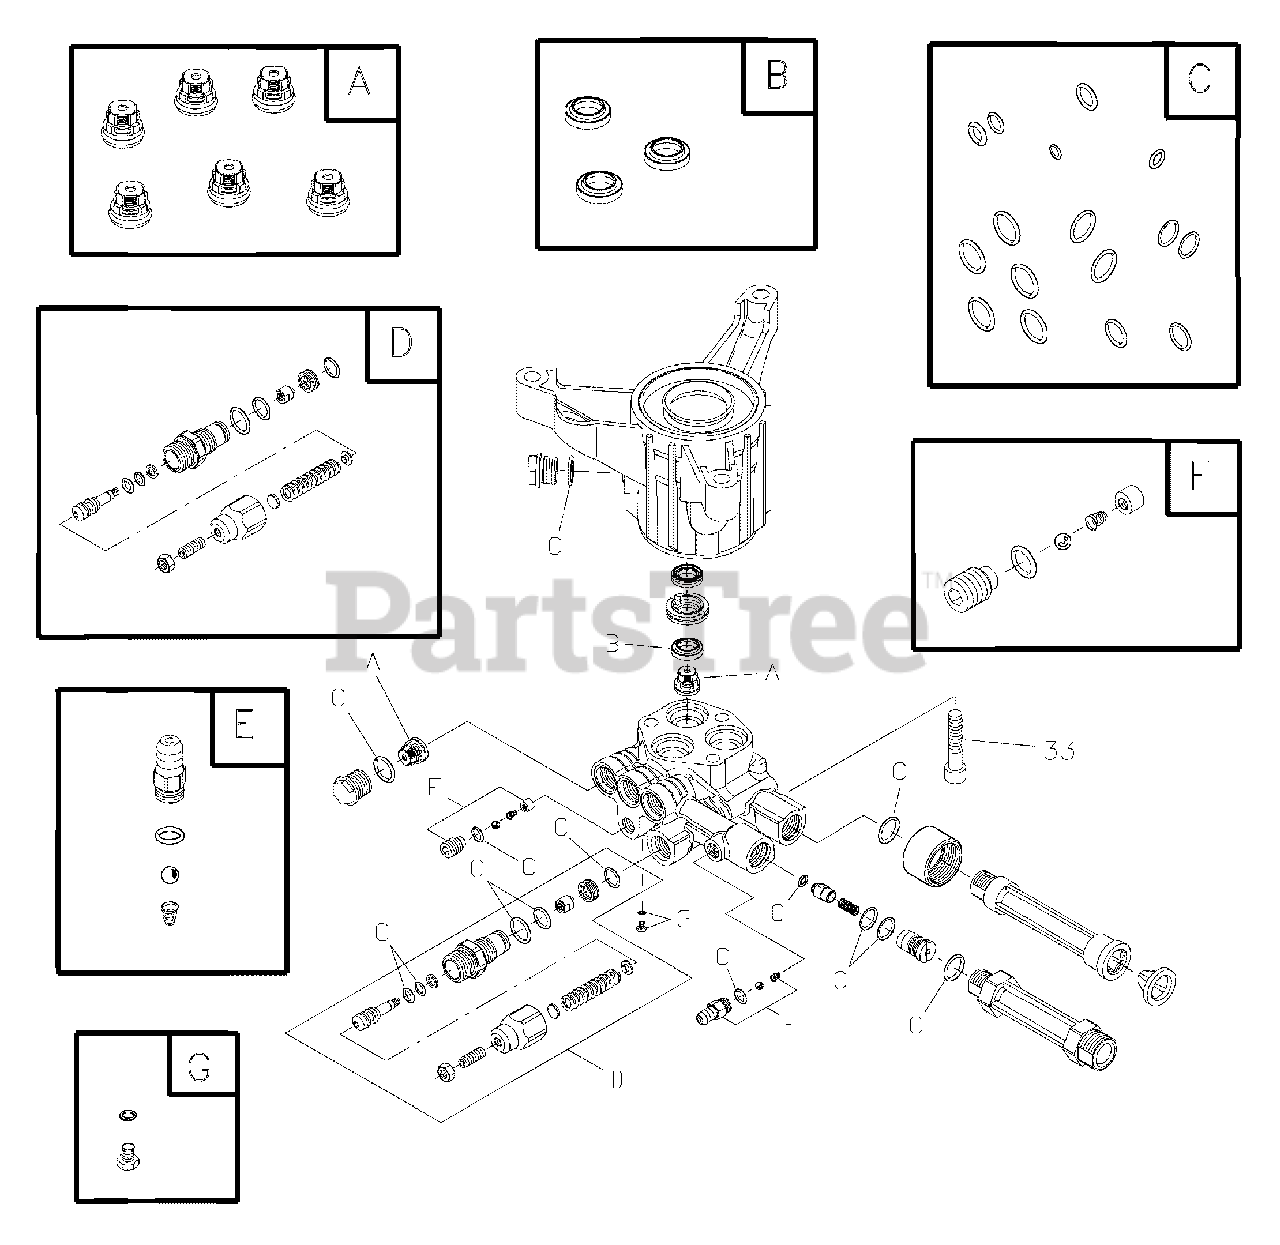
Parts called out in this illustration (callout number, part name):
33	SCREW
B	KIT, WATER SEALS
D	KIT, UNLOADER
G	KIT, GRUB SCREW & WASHER
